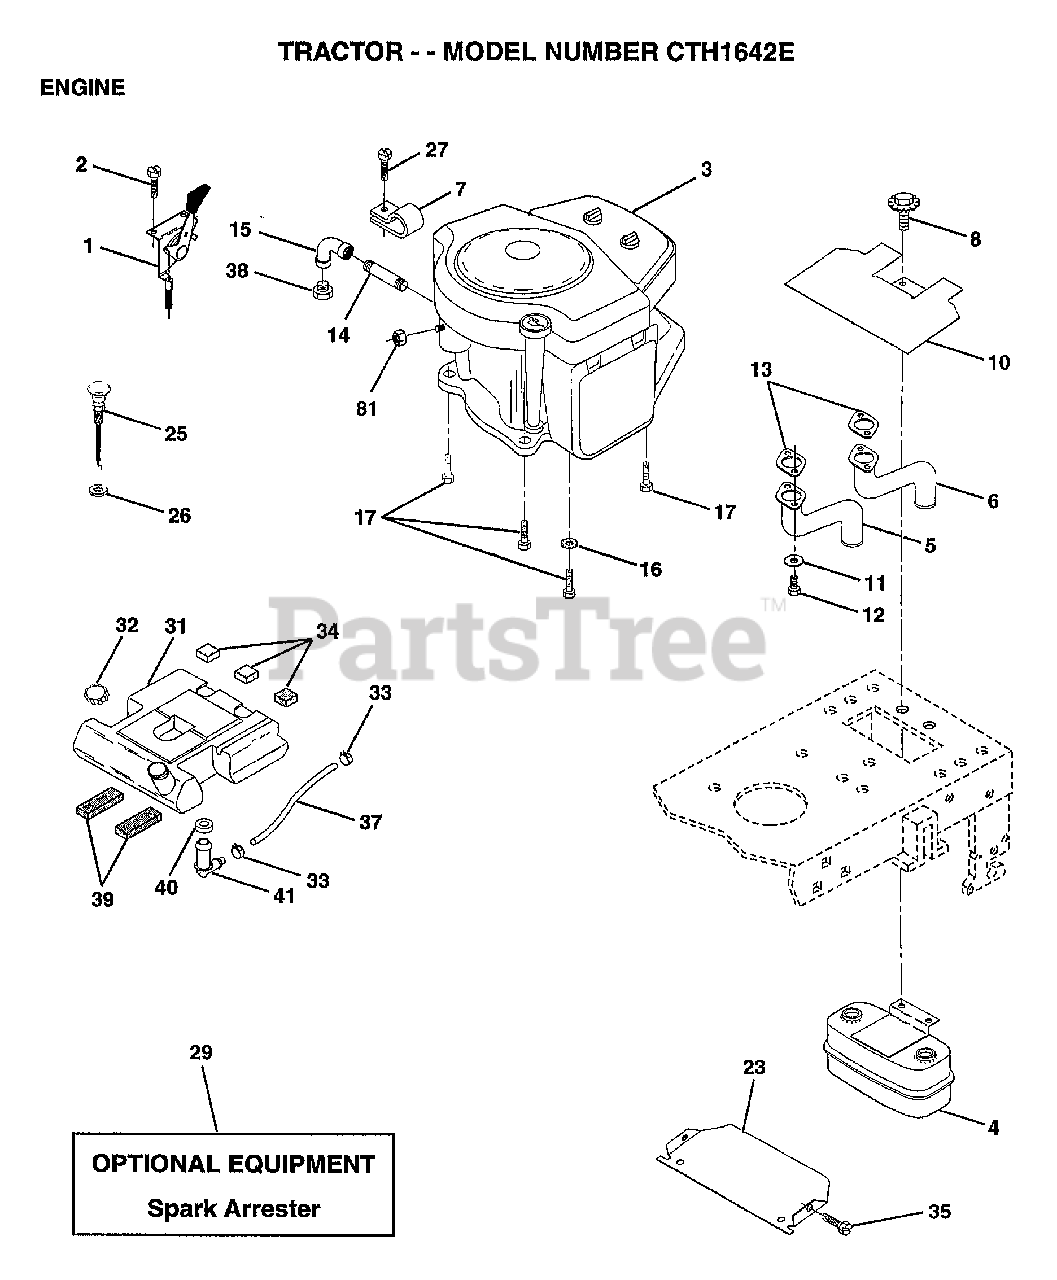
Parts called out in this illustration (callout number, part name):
2	SCREW LT
3	ENGINE, BRIGGS
4	MUFFLER.TW.LOTONE
5	EXHAUST.B&S.18.LH
6	EXHAUST.B&S.18.RH
7	CLAMP.TUBE.DBL.EN
8	BOLT.5/16-18.UNC
10	SHIELD.HEAT.
11	LOCKWASHER
13	GASKET MUFFLER
14	PIPE NIPPLE LT
15	ELBOW
16	LOCKWASHER
17	SCREW LT
23	SHIELD-HEAT
25	"CONTROL.CHOKE.51"""
26	"NUT,KEPS 3/8-24IM"
27	"SCREW-TT,10-32 FL"
31	TANK FUEL REAR
32	CAP ASM FUEL
33	HOSE CLAMP
34	PAD-SPACER LT
35	SCREW
37	FUEL LINE T
39	PAD IDLER TI
40	BUSHING OUTLET T
41	STEM.TANK.FUEL
81	NUT
